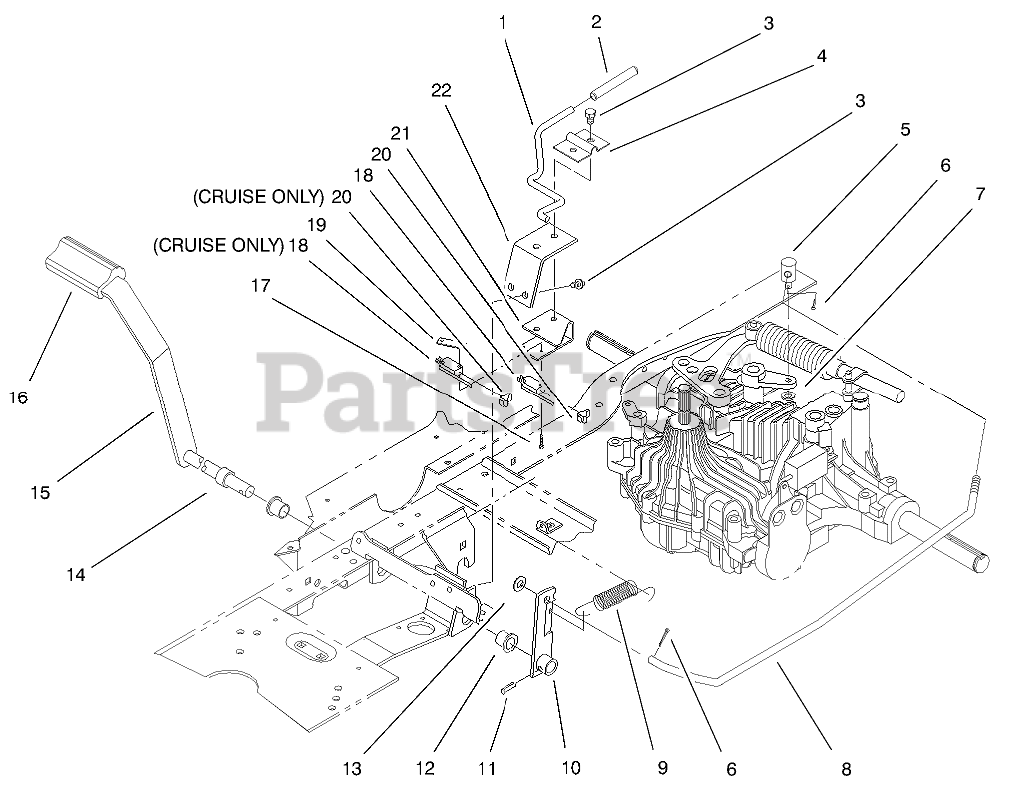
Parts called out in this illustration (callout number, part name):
1	ROD - PARKING BRAKE
2	GRIP - PARKING BRAKE
3	SCREW-HWHTF
4	BRKT-PARKING BRAKE
5	TRUNNION - BRAKE
6	PIN-COTTER
7	WASHER-PLAIN
8	ROD - BRAKE
9	SPRING-EXTENSION
10	WA - BRAKE LEVER
11	PIN-SPRING
12	BUSHING-FLANGE
13	WASHER-FLAT
14	SPACER-BRAKE
15	LEVER - BRAKE WA
16	PAD-PEDAL
17	SCREW-HH
18	SWITCH-MICRO
19	NUT-SPEED
20	PLUNGER-SEAL
21	BRKT - BRAKE SWITCH
22	SUPPORT - P. BRAKE
